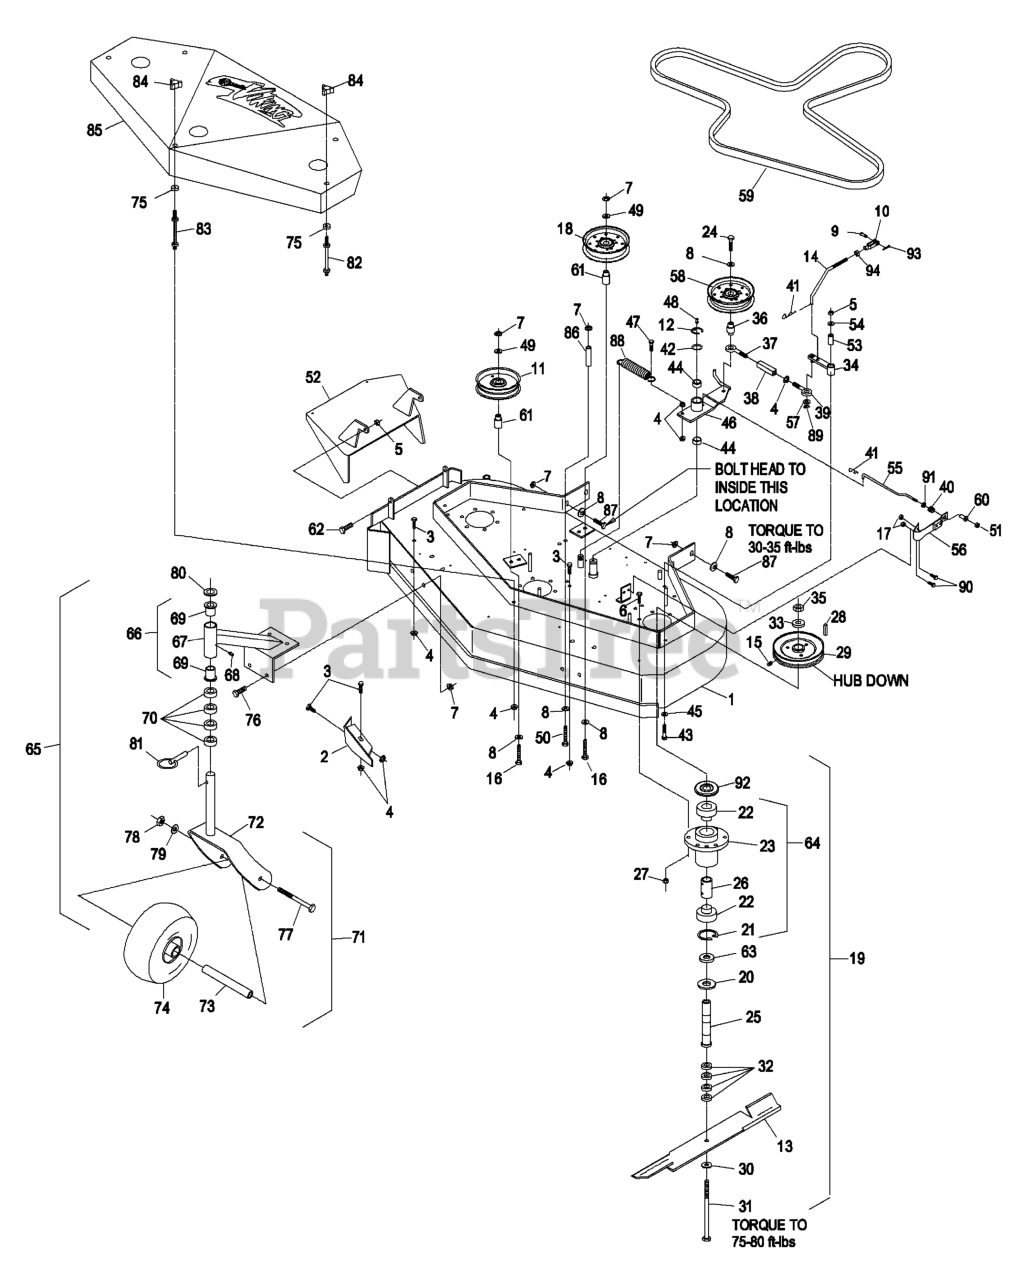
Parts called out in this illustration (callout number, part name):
1	DECK-SERVICE, 48
2	BAFFLE-DOGLEG
3	SCREW-HH
5	NUT-LOCK, NI
6	SCREW-HH
7	NUT-HHF, WHIZ
8	WASHER-BELLEVILLE
9	PIN-CLEVIS
10	YOKE-ADJUSTABLE
11	PULLEY-IDLER
12	RING-RETAINING, EXT
14	ARM-LINKAGE, ASSIST
15	SCREW-SET
16	SCREW-HH
17	NUT-LOCK, NI
20	GUARD-BEARING, BOTTOM
21	RING-SNAP
22	BEARING
24	SCREW-HH
25	TUBE-SPINDLE, SHORT
26	SPACER-BEARING
27	NUT-LOCK, NI
30	WASHER-SPRING
31	SCREW-CAP, HH
33	WASHER-RETAINER, SHEAVE
34	ARM-ASSIST
35	NUT-HEX
36	BUSHING-ENGAGEMENT
37	EYEBOLT-THREAD, LH
38	BODY-TURNBUCKLE
39	EYEBOLT-THREAD, RH
40	SPRING-COMPRESSION
41	PIN-COTTER
42	WASHER-SPINDLE
43	SCREW-HH
44	SLEEVE-BEARING
45	WASHER-SPRING
46	ENGAGE ARM ASM
47	SCREW-HH
48	FITTING-GREASE
49	WASHER-FLAT
50	SCREW-HH
51	NUT-LOCK, NI
52	WLD,CHUTE 48
53	TUBE-PIVOT
54	WASHER-FLAT
55	ROD-BRAKE
56	PAD AND SPRING ASM
57	WASHER-PLAIN
59	BELT,BLADE 48
60	SPACER-FLANGED
62	SCREW-HH
63	SPACER-PULLEY/BEARING
66	ASM,CSTR SUPPORT W/WEIGHT
68	FITTING-GREASE
69	BEARING-FLANGED
70	SPACER-CASTER
71	ASM,CASTER/WHEEL
73	SPACER FRONT CASTER
76	SCREW-HH
77	SCREW-HH
78	NUT-HH
79	WASHER-LOCK
80	WASHER-FLAT
82	STUD-SHIELD, BELT (SHORT)
83	STUD-SHIELD, BELT (LONG)
84	KNOB-3 PRONG
87	SCREW-HH
88	SPRING-EXTENSION
89	RING-RETAINING, EXT
90	SCREW-HH
91	RING-PUSH ON
92	GUARD-BEARING, TOP
93	PIN-COTTER
94	NUT-HEX
95	KIT, SP CASTER WHEEL REPL
